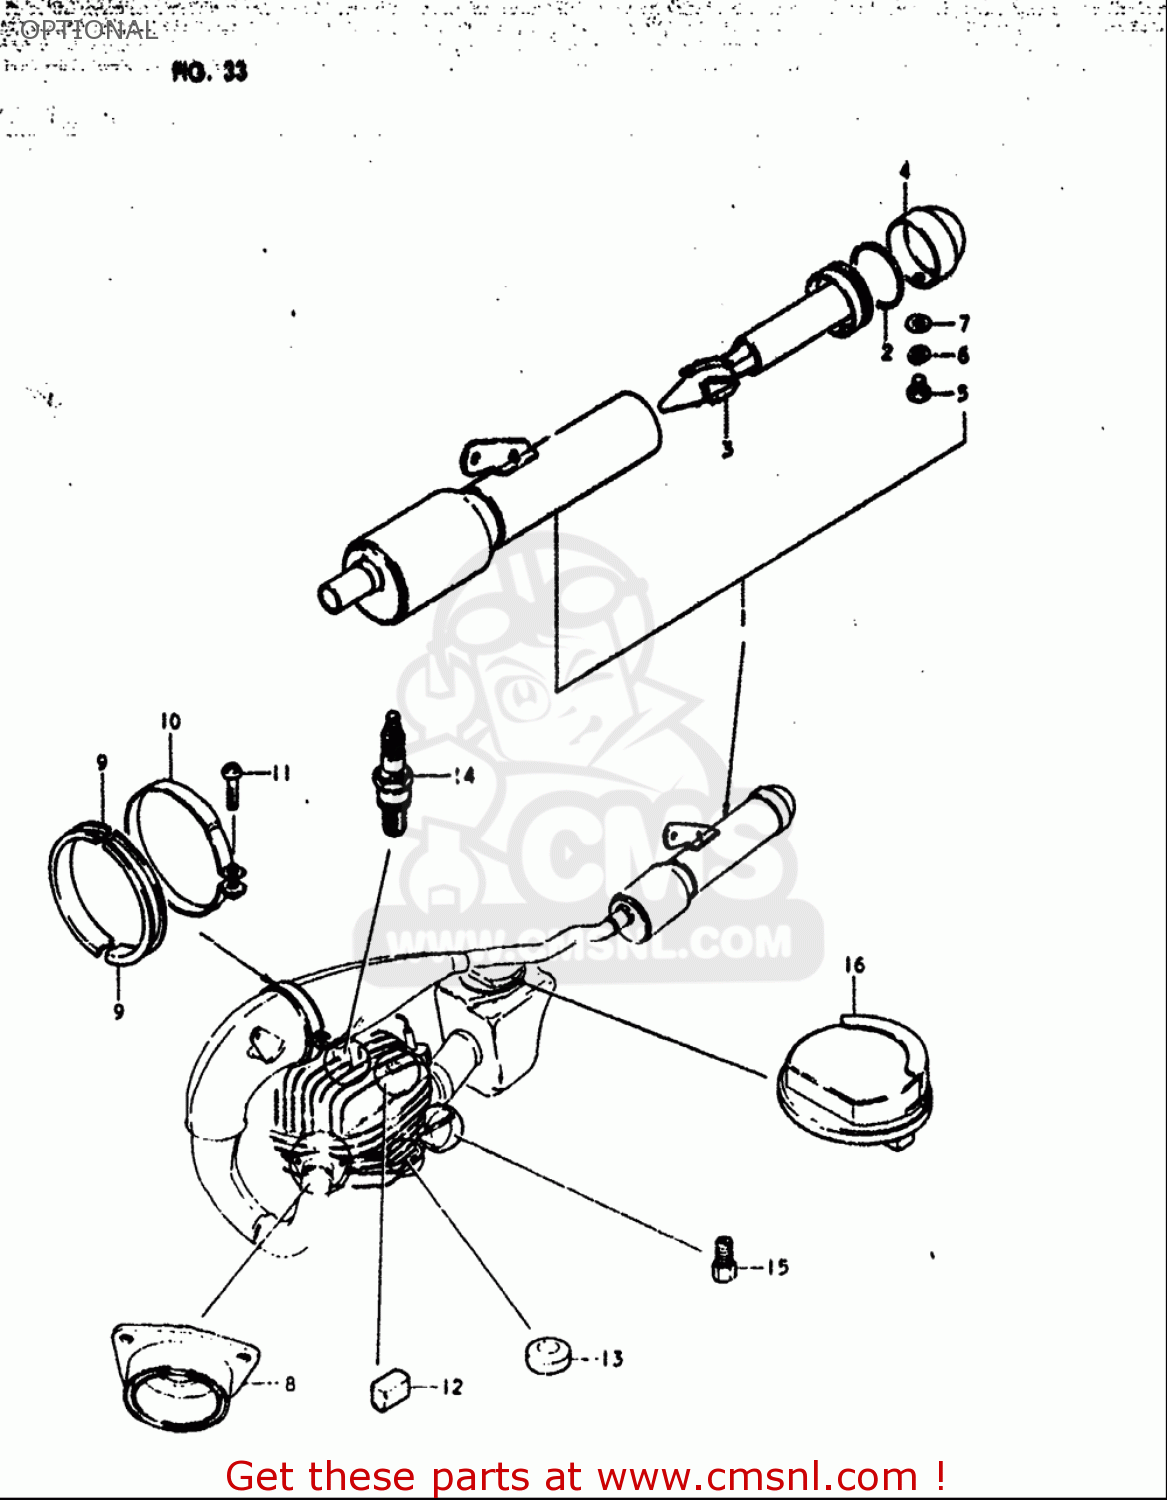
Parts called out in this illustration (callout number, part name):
5	SCREW(6X8)
6	WASHER,LOCK
7	WASHER
10	CLAMP
11	SCREW
12	PAD,CYLINDER
13	PAD,CYLINDER RUBBER(N1)
14	PLUG,SPARK(NGK B-8EN)
15	JET,MAIN(140)
